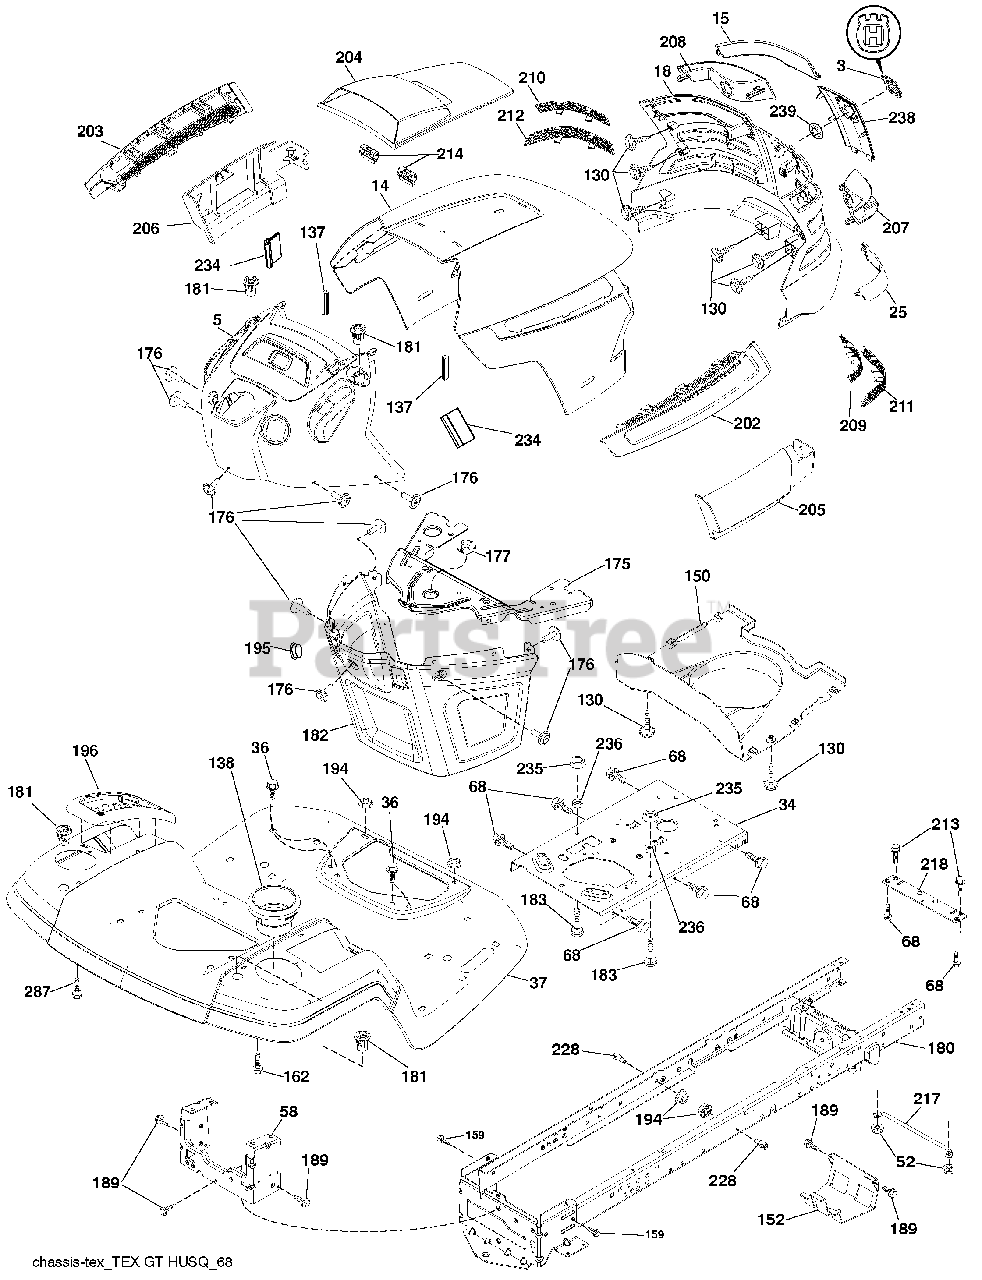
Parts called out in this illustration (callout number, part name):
3	Logo
14	Hood
18	Grille/Lens Asm.
34	Plate Engine
36	Screw 5/16-18 x 3/4
37	Fender
52	Nut Lock 5/16-18
58	Drawbar Upper 2PC Sml. Fender
68	Screw Thdrol 5/16-18 x 1/2
130	Screw #10 x 0.750
137	Bumper Dash
138	Cupholder
152	Shield Browning
159	Screw Hexwsh Thrd 3/8-16 x 3/4
175	Crossmember Plate
176	Screw 10-24 x 5/8
177	Bushing Steering
181	Bushing Mtg. Fender Crgo
182	Dash Lower
183	Bolt Fin Hex 5/16-18 unc x 1-1/4
189	Screw 5/16-18 x 3/4
194	Nut Lock Hex Flange 5/16-18
195	Plug Hole Dash Lower
196	Console Asm. Deck Lift
202	Vent Side Hood RH
203	Vent Side Hood LH
204	Vent Top Hood
205	Skirt Hood Side RH
206	Skirt Hood Side LH
209	Insert Hex Top RH
210	Insert Hex Top LH
211	Insert Hex Bottom RH
212	Insert Hex Bottom LH
213	Bolt 5/16-18 x 3/4
214	Clip Retainer Tinner
218	X-Piece Hood Stop
228	Stud Fastner
234	Bumper Hood
235	Spacer Fender
236	Nut Lock 5/16-18 unc
287	Screw 1/4-20 x 3/8
